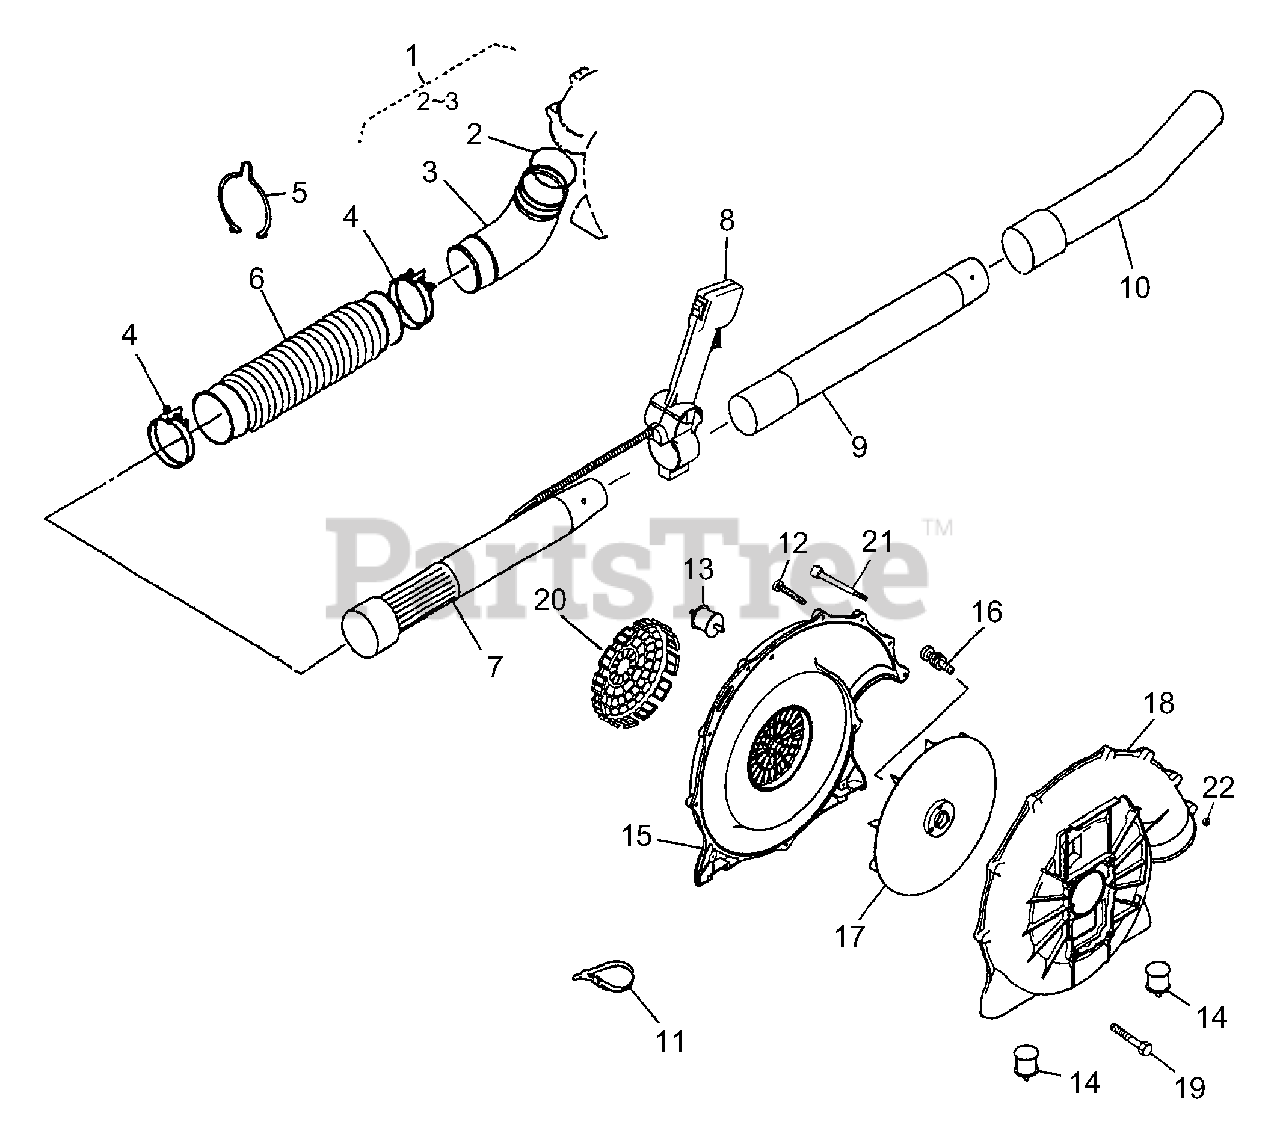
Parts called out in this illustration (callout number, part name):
1	Elbow Pipe
2	O-Ring
3	Elbow Pipe
4	Hose Band
5	Wire Clamp
6	Flexible Pipe
7	Base Pipe
8	Throttle Lever Assy.
9	Middle Pipe
10	Bend Pipe
11	Wire Band
12	Tapping Screw (M5x20)
13	Rubber AV Mount
14	Rubber AV Mount
16	Pre-Coat Lock Bolt
19	Pre-Coat Lock Bolt
20	Fan Cover
21	Socket Screw
22	Nylon Nut
